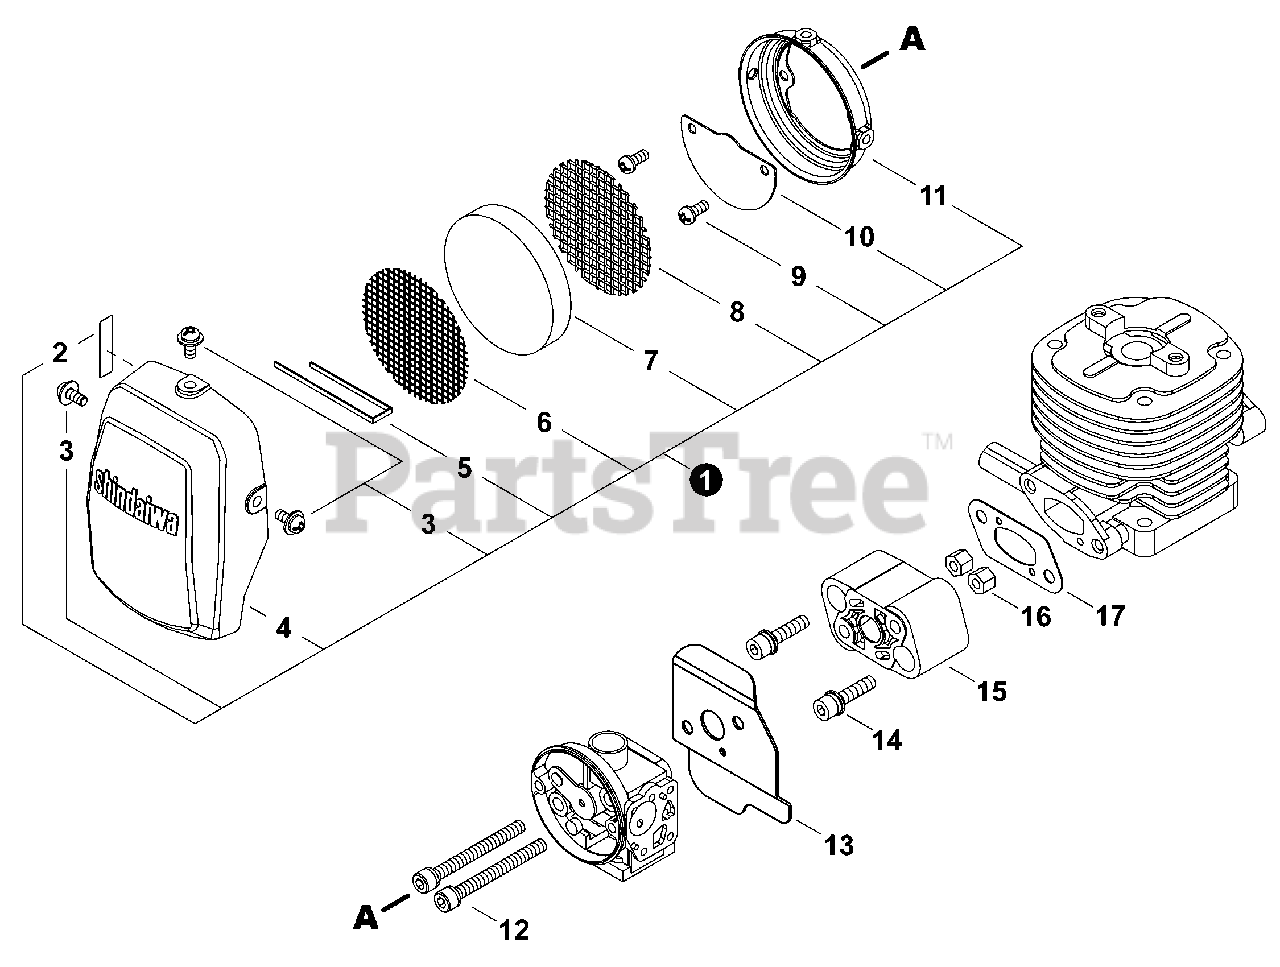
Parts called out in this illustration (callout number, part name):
1	FILTER ASSY, AIR
2	LABEL, CHOKE
3	SCREW 4
4	COVER, AIR FILTER
5	CLIP, FILTER RETAINING
6	SCREEN - FRONT
7	FILTER, AIR
8	SCREEN, REAR
9	SCREW
10	PLATE
11	CASE, AIR FILTER
12	BOLT M5×48
13	GASKET, CARBURETOR
14	BOLT M5×25
15	INSULATOR
16	NUT M5×6.3
17	GASKET, INTAKE
